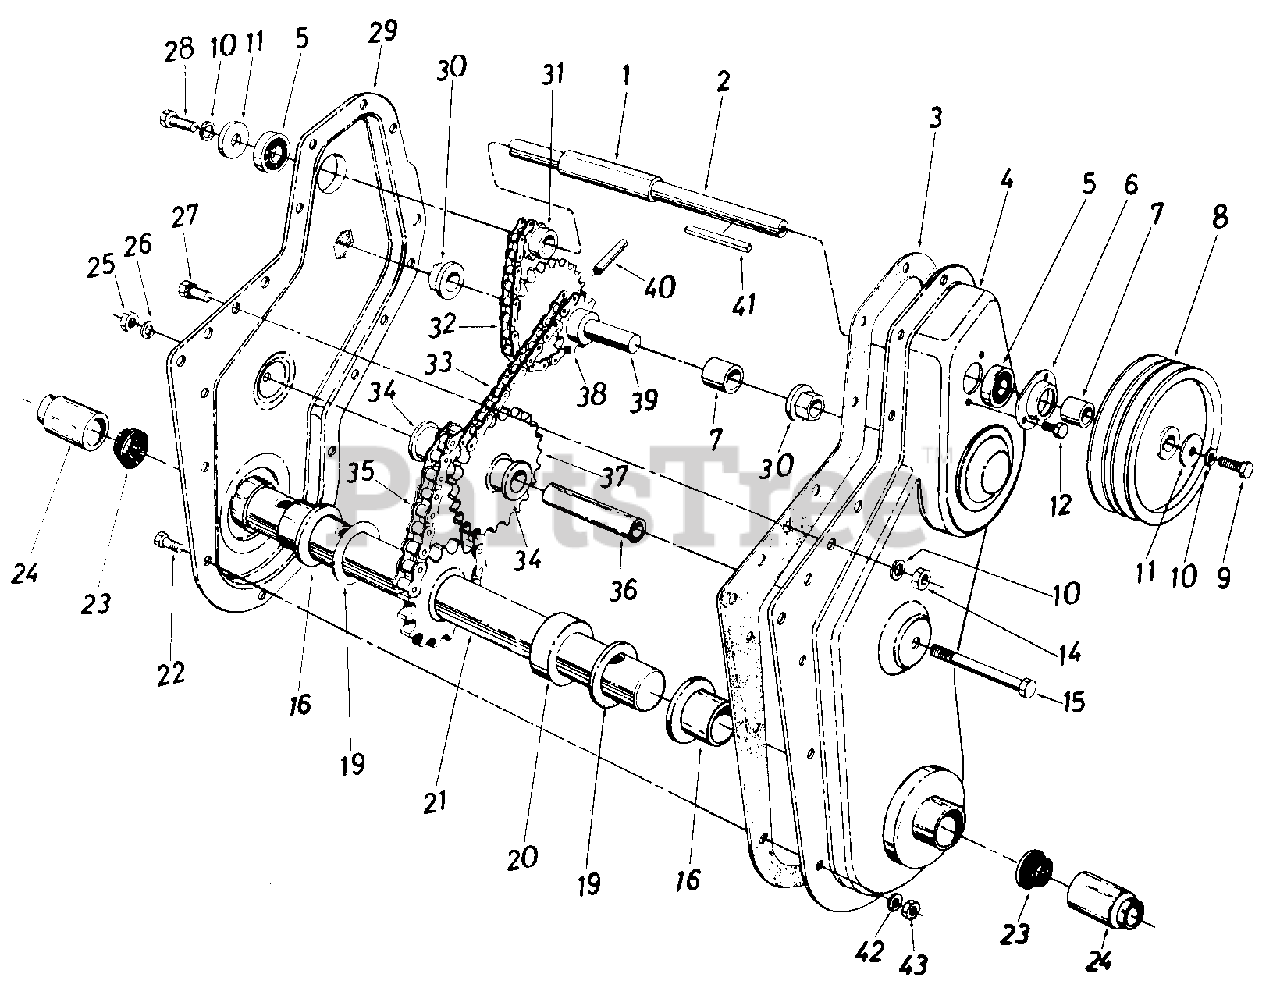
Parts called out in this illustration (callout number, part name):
1	Spacer .657 I.D. x .78 O.D. x 2.19" Lg.
2	Jackshaft
3	Housing Gasket
4	Housing Ass'y.-L.H. Half
5	Ball Bearing .625 I.D. x 1.375 O.D.
6	Bearing Housing
7	Spacer .635 I.D. x .88 O.D. x 1.03" Lg.
8	Chain Case Pulley 6.0" Dia.
9	Hex Bolt 5/16-18 x 1.0" Lg.
10	L-Wash. 5/16" I.D.
11	Fl-Wash. .344" I.D. x 1.125" O.D.
12	Hex Wash. Hd. Self-Tap Scr. 1/4-20 x .50" Lg.
14	Hex Nut 5/16-18 Thd.
15	Hex Bolt 3/8-16 x 3.25" Lg.
16	Flange Bearing (Plastic)
19	Flat Thrust Wash.
20	Step Spacer
21	Tine Shaft Ass'y.
22	Hex Bolt 1/4-28 x .62" Lg.
23	Seal Ring
24	Dust Cap
25	Hex Nut 3/8-16 Thd.
26	L-Wash. 3/8" I.D.
27	Hex Sems Bolt 5/16-18 x 1.00" Lg.
28	Hex Bolt 5/16-18 x .62" Lg.
29	Housing Ass'y.-R.H. Half
30	Hex Flanged Bearing
31	Sprocket 10 Teeth 1/2" Pitch
32	#41 Chain 1/2" Pitch x 34 Links
33	#420 Chain 1/2" Pitch x 48 Links
34	Flange Bearing .625" I.D.
35	#50 Chain 5/8" Pitch x 28 Links
36	Sprocket Shaft
37	Sprocket Bearing Sleeve Ass'y.
38	Sprocket Sleeve Ass'y.
39	Sprocket Shaft
40	Spring Pin Spiral 1/4" Dia. x 1.5" Lg.
41	Square Key 3/16 x 3/16 x 1.50" Lg.*
42	L-Wash. 1/4" I.D.
43	Hex Nut 1/4-28 Thd.
